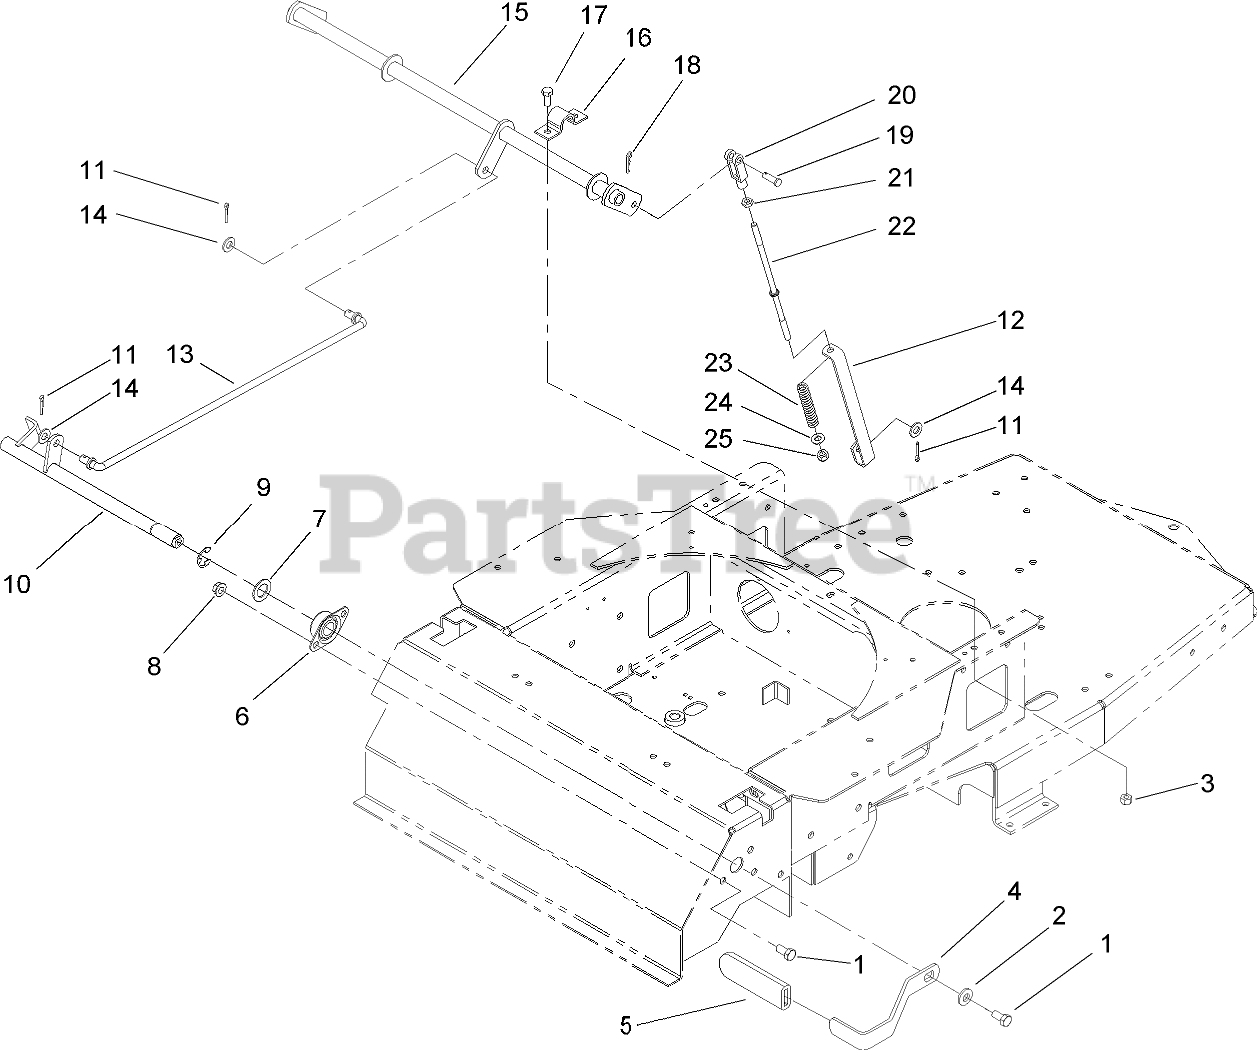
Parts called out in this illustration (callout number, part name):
1	SCREW-HH
2	WASHER-BELLEVILLE
3	NUT-LOCK, NI
4	HANDLE-BRAKE, PARK
5	GRIP-LEVER
6	BEARING-FLANGE, SIDE
7	WASHER
8	NUT-HHF, WHIZ
9	E-RING
10	BRAKE SHAFT ASM
11	PIN-COTTER
12	BRACKET-SPRING, BRAKE
13	ROD-BRAKE, UPPER
14	WASHER-FLAT
15	SHAFT-BRAKE
16	CLAMP-PIVOT, HOC
17	SCREW-HH
18	PIN-COTTER
19	PIN-CLEVIS
20	YOKE-ADJUSTABLE
21	NUT-HEX
22	ROD-BRAKE, UPPER
23	SPRING
24	WASHER-PLAIN
25	NUT-LOCK
